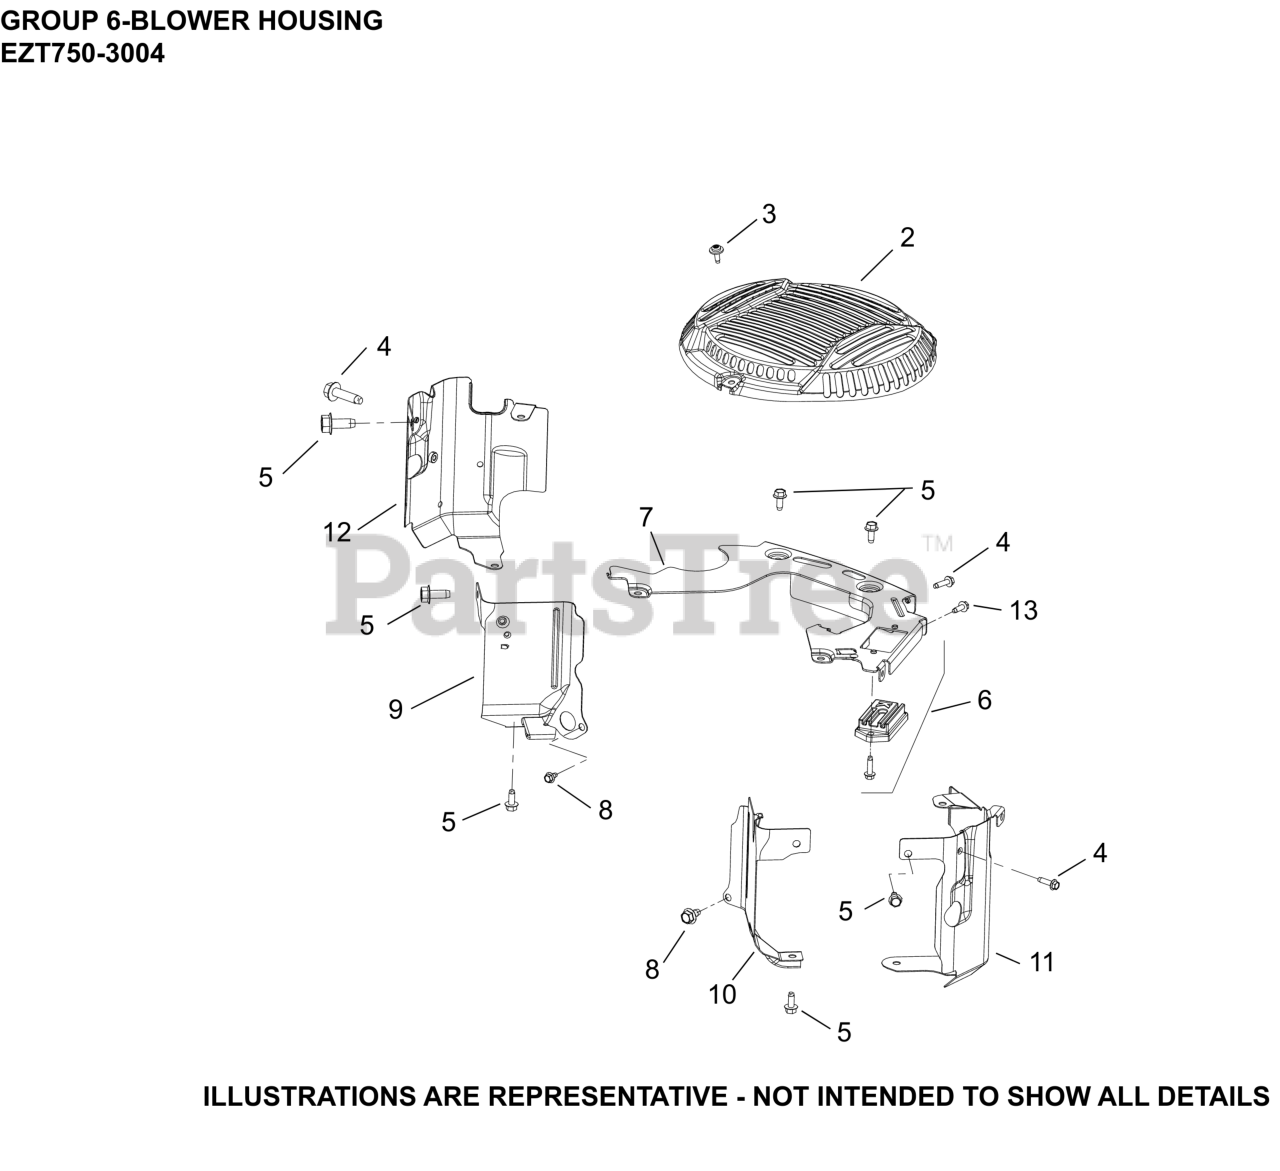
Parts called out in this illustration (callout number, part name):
2	GUARD, GRASS SCREEN (METAL)
3	SCREW, SEMS
4	SCREW, THD FRM-USE 25 086 473-S
5	SCREW, THREAD FORMING
6	PLATE ASSEMBLY, BACKING (15A)
7	PLATE, BACKING
8	SCREW, THREAD FORMING
9	BAFFLE, VALLEY #1
10	BAFFLE, VALLEY #2
11	BAFFLE, LEFT BARREL
12	BAFFLE, RIGHT BARREL
13	SCREW, THREAD FORMING
NI	KIT, BLOWER HOUSING
